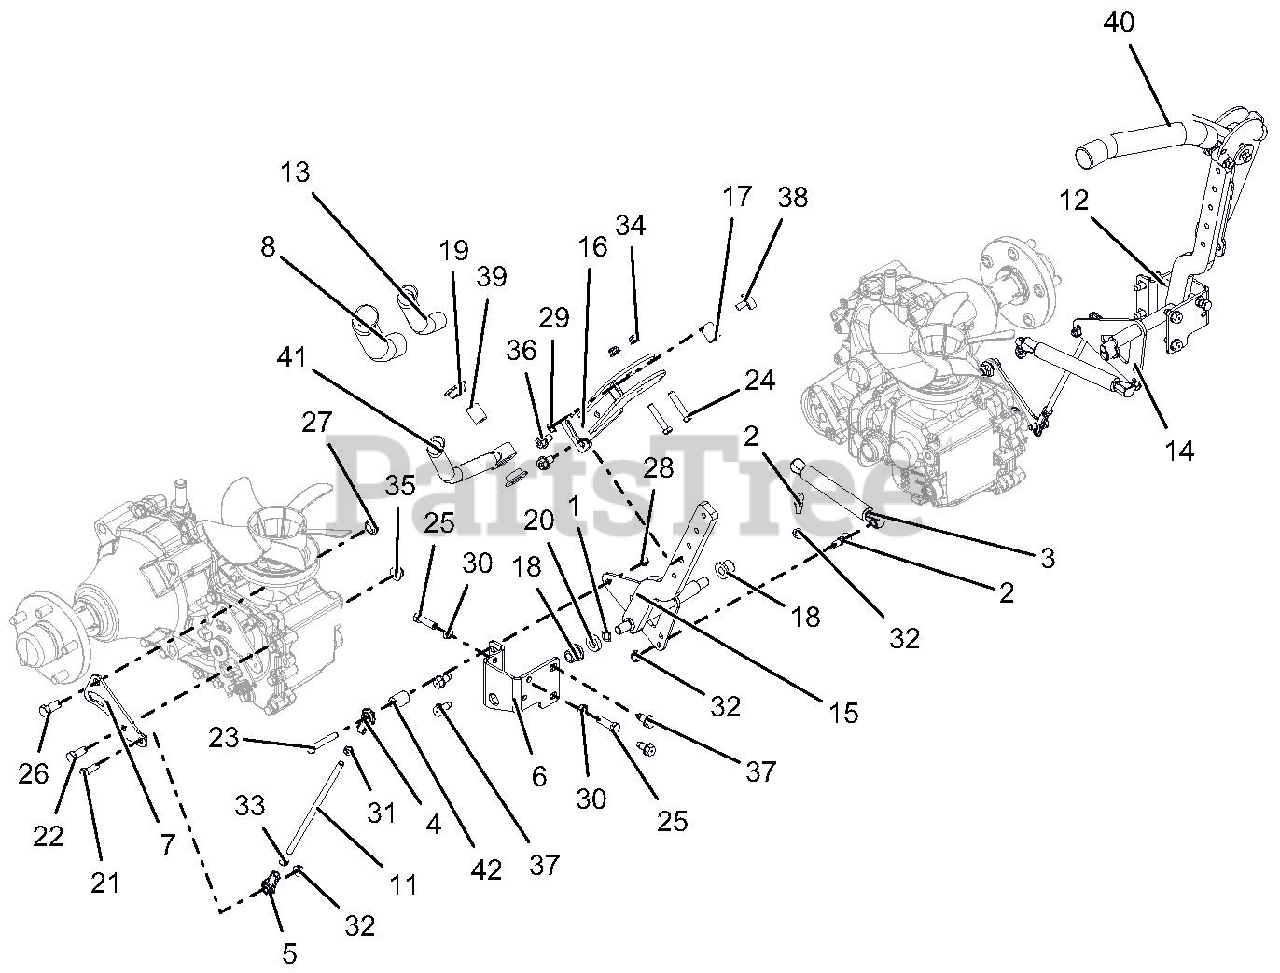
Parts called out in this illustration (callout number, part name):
1	WAVE WASHER .531X.781X.125 FH
2	STUD-BALL
3	DAMPER,
4	ALIGNABALL, 5/16 RH THREAD
5	ALIGNABALL, 5/16 LH THREAD
6	BRKT, RH CONTROL STOP
7	BRKT., CONTROL MTG
8	GRIP, HANDLEBAR
11	ROD, STEERING
12	BRKT, LH CONTROL STOP
13	TUBE, .88ID X 1.00OD X 10.25
14	WLDMT, LH LOWER CONTROL ARM
15	WLDMT, RH LOWER CONTROL ARM
16	WLDMT, ADJUSTABLE STEERING HANDLE MOUNT
17	BSHG, ECCENTRIC .328 X .750 X .970
18	BHSG-FLG .500X.750X.750X.125
19	BSHG, FLANGE .762 X 1.48 X .44 NYLON
21	BLT-HEX .31-18X1.00 GR5 YWZC
22	BLT-HEX .38-16X1.00 GR5 YWZC
23	BLT-HEX .31-18X2.00 GR5 YWZC
24	BLT-HEX .31-18X1.75 GR5 YWZC
25	BLT-HEX .38-16X1.25 GR5 YWZC
26	BLT-HEX .44-14X1.00 GR5 YWZC
27	NUT-LK-NYL-FLG .44-14 YWZC
28	NUT-LK-CTR .31-18 YWZC
29	@NUT-SPNLK-FLG .312-18 YWZC
30	NUT, JAM .375-16 YWZC
31	NUT-JAM
32	NUT, LK-TOP-FLG .312-18 YWZC
33	NUT, JAM -LH .31-24 YWZC
34	NUT-LK-NYL-FLG .31-18 YWZC
35	NUT-LK-NYL-FLG .38-16 YWZC
36	BLT-SERHFWH .38-16X.62 YWZC
37	SCR-TAP .38-16X.75 HWH TR YWZ
38	BUMPER, RUBBER
39	SPACER, .328 X .76 X 1.01
40	WLDMT, LH HANDLE
41	WLDMT, RH HANDLE
42	ECCENTRIC
